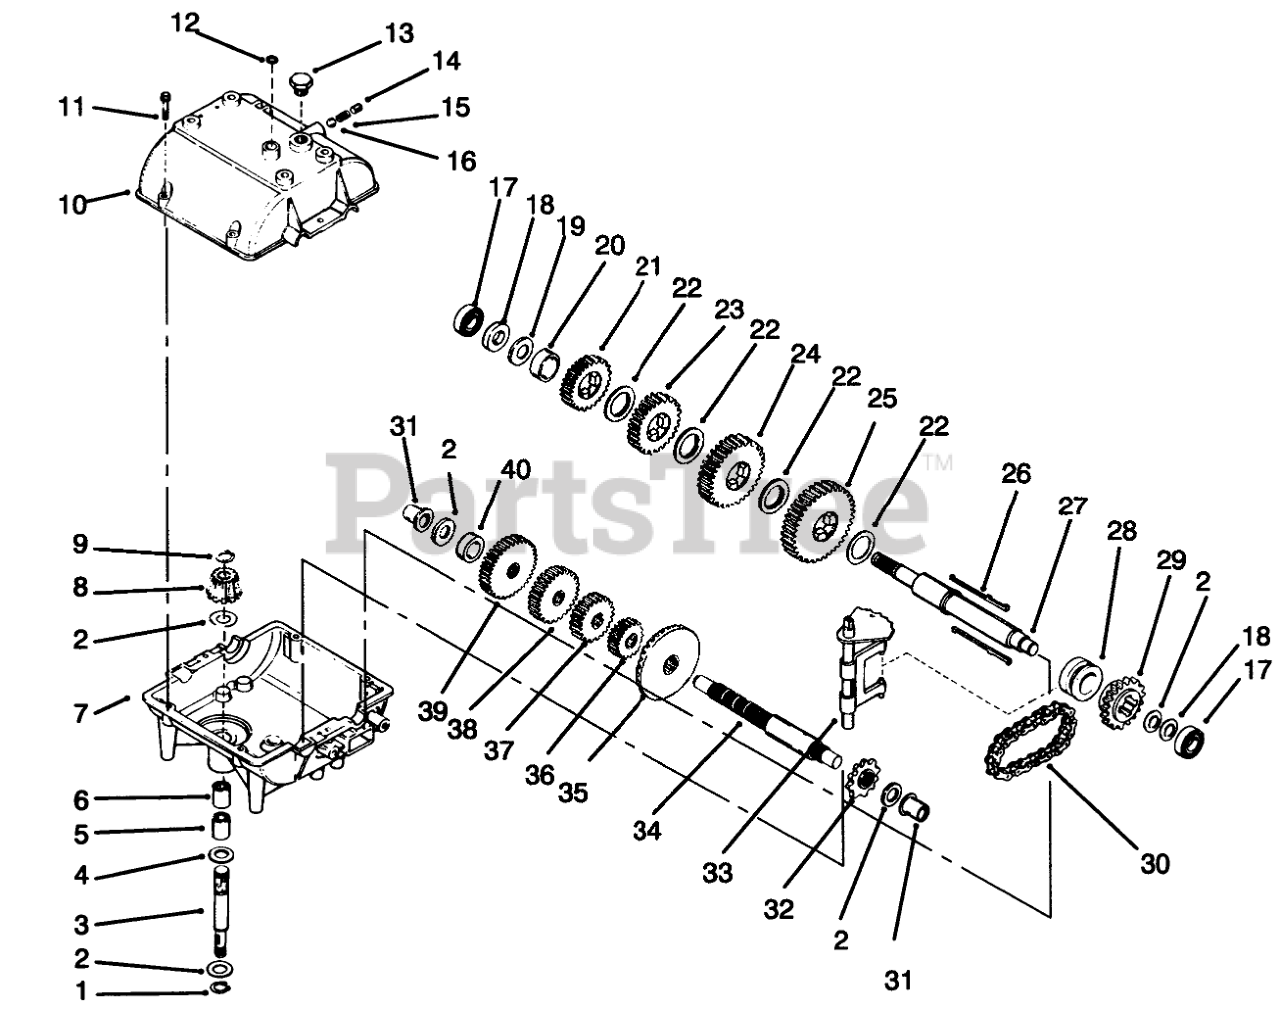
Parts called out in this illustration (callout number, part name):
1	Ring-Snap
2	Washer
3	Shaft-Input
4	O Ring
5	Bearing-Needle
6	Bearing-Needle
7	Case-Transmission
8	Bevel Pinion-Input
9	Ring-Retainer
10	Cover-Transmission
11	Ring Set (.020 O S)
12	Cut Seal-Square
14	Screw-Set
15	Spring
16	Ball-Steel
17	Bearing-Ball
18	Thrust Washer
19	Washer
20	Spacer
21	Gear-Spur, 25 Teeth
22	Washer
23	Gear-Spur 27 Teeth
24	Gear-Spur, 30 Teeth
25	Gear-Spur, 35 Teeth
27	Shaft-Output/Brake
28	Collar-Shift
29	Sprocket-18 Teeth
30	Chain-Roller #41
31	Bushing-Flange
32	Sprocket-9 Teeth
33	Rod and Fork ASM
34	Countershaft
35	Gear-Bevel, 42 teeth
36	Gear-Spur 15 Teeth
37	Gear-Spur, 20 Teeth
38	Gear-Spur 23 Teeth
39	Gear-Spur, 25 Teeth
40	Spacer
